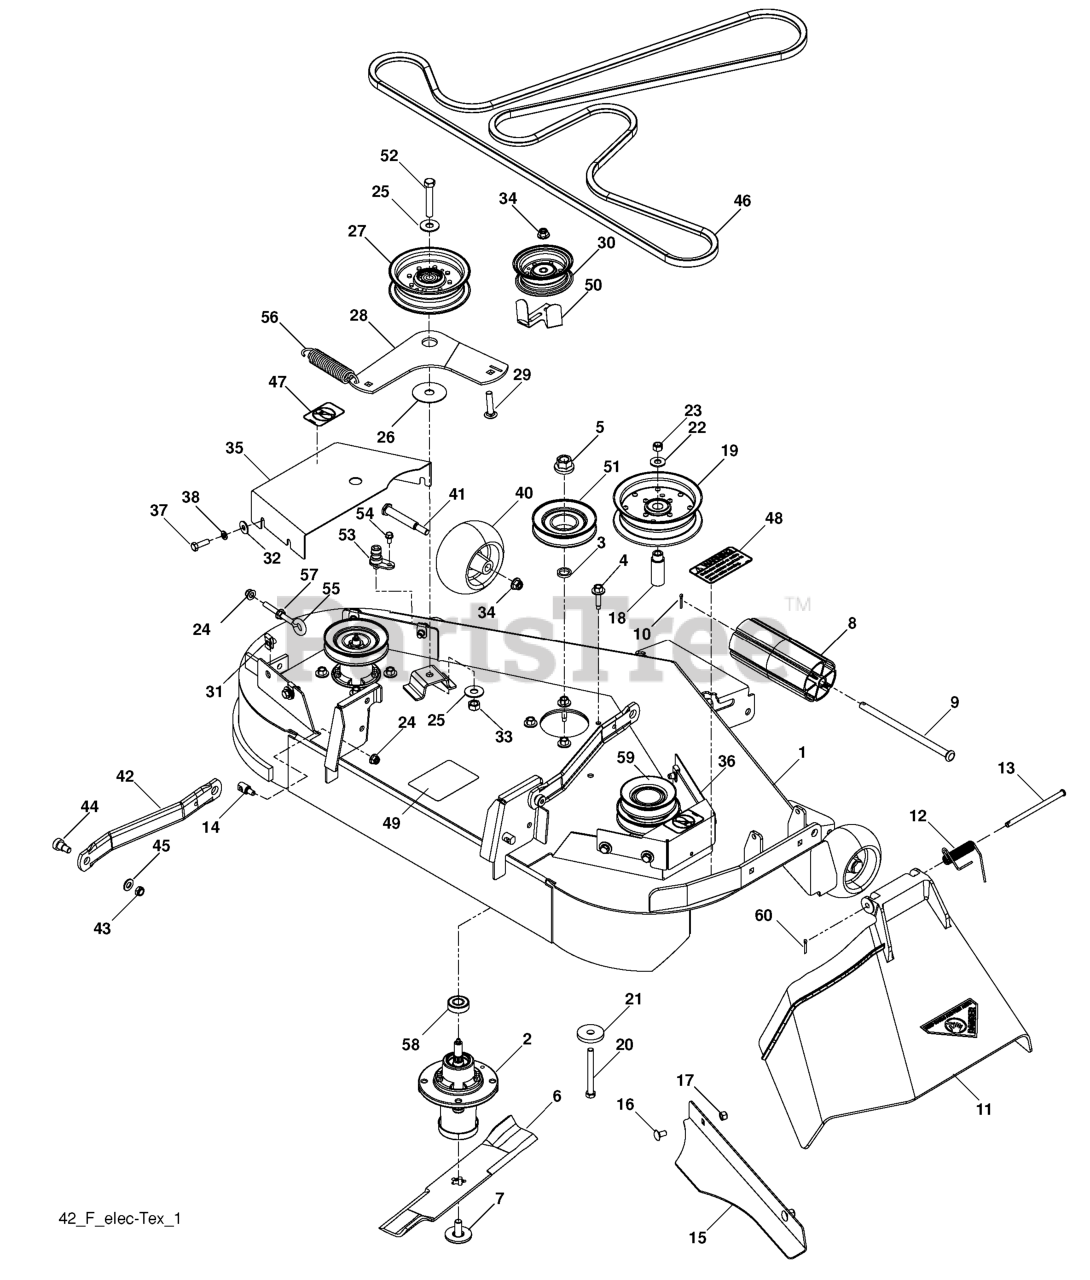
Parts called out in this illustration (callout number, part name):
1	DECK SVC W/DECALS 42 YTH ORNGE
2	MANDREL.DECK.ASSEMBLY
3	WASHER-SPACER
4	WASHER HEAD SCREW
5	LOCKNUT - 9/16
6	BLADE, 14 5/8"
7	BLADE BOLT ASSY-7/16" TB REPL
8	NOSE ROLLER 48"
9	ROD.ROLLER.NOSE.NARROW.48"
10	PIN.COTTER.5/16.BOW TI
11	DISCHARGE CHUTE - 42 PLASTIC
12	SPRING - TORSION
13	PIN, CLEVIS 5/16 X 5.19
14	STUD.FASTNER.W/ANTI-ROTATE
15	CONFINEMENT.PLATE.42".BLACK
16	CARRIAGE BOLT 5/16C X 5/8"
17	NUT 5/16 NYLOC
18	BUSHING, IDLER
19	PULLEY, IDLER
20	HCS 3/8-16 X 3-1/2 GR5 ZD
21	SPINDLE WASHER
22	WASHER 3/8 FLAT
23	NUT 3/8-16 NYLOC
24	5/16-18 NYLOC FLANGE NUT
25	WASHER 7/16 FLAT ZD
27	PULLEY.IDLER.MWR.STATI.LH
28	ARM, IDLER, BLK
29	RHSNB 3/8-16X1-3/4
30	PULLEY.IDLER.FLAT
31	U-CLIP 5/16-18 NUT RETAINER
32	WASHER 5/16 FLAT
33	7/16-14 HEX NUT W/NYL RING ZD
34	NUT 3/8-16 HEX FLG NYLOC ZD
35	SHIELD.BELT.LH.ORANGE
36	SHIELD.BELT.RH.ORG
37	HCS 5/16C X 1
38	WASHER.LOCK.HVY.HLCL.SPR.5/16
40	GAUGE WHEEL
41	SHOULDER BOLT 1/2X2-5/8 ZD SPE
42	ARM.SUSPENSION.MOWER
43	NUT HEX 3/8-16 NYLON, THIN
44	SB 3/8-16 X 3/8 SKT HD ZD
45	WASHER 3/8 SAE FLAT
46	BELT, 42" FAB DECK
47	DECAL, NO STEP
48	DECAL, CAUTION
49	DECAL.MOWER.SCH.48/54
50	BELT GAURD
51	PULLEY, MANDREL 4.08 OP
52	BOLT 7/16-14 X 2-1/2 GR 5 ZD
53	PORT.WASHOUT
54	BOLT 1/4-20 X 1/2 HWST
55	EYE BOLT 5/16 X 3.50
57	NUT 5/16C WHIZ
58	BEARING, BALL
59	PULLEY, COLLECTION 42
60	RETAINER CLIP
